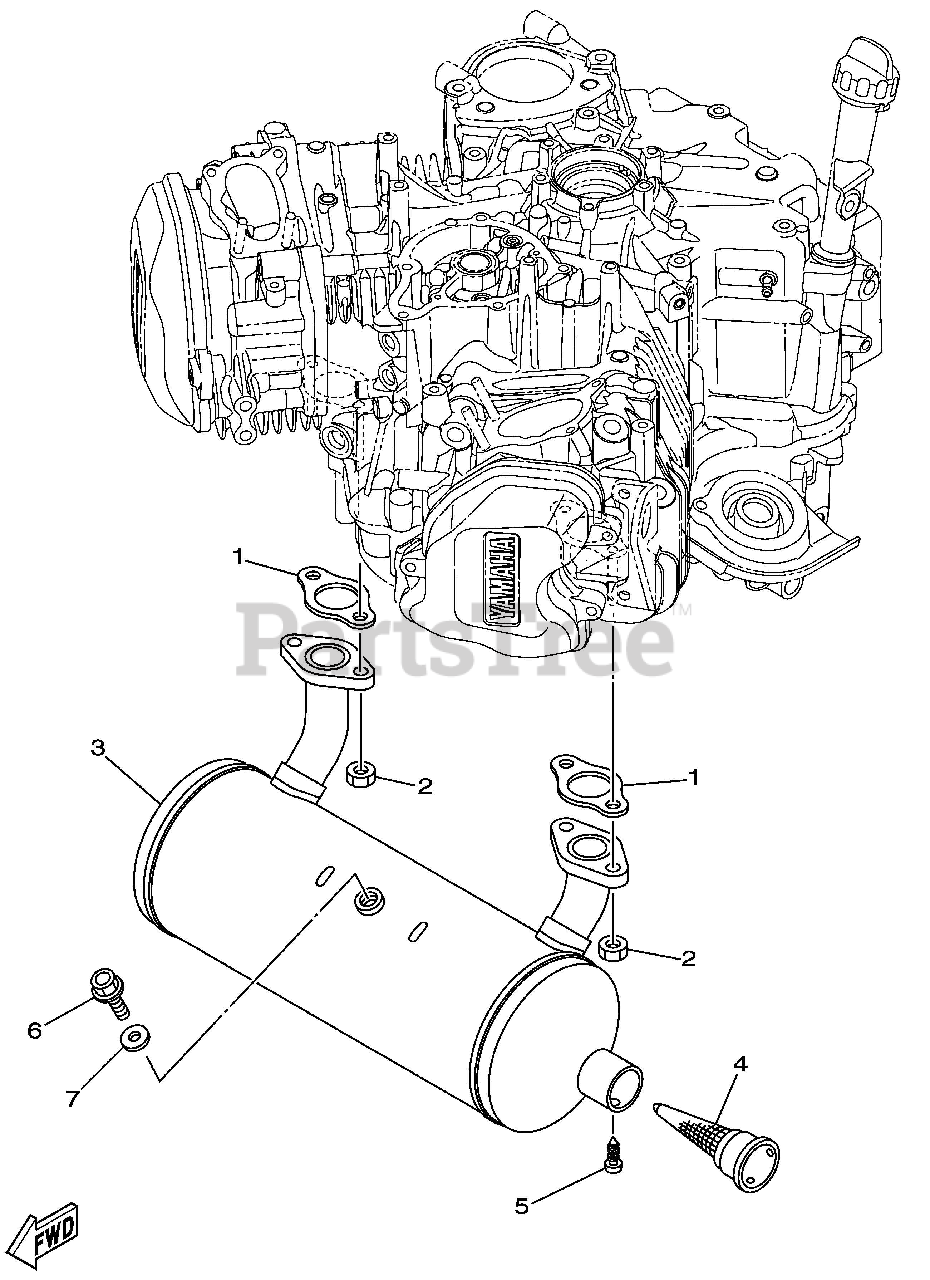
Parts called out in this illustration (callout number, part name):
1	GASKET, MUFFLER YAMAHA 824
2	NUT, HEXAGON
4	ARRESTER, SPARK
5	SCREW, TAPPING
6	BOLT, FLANGE
